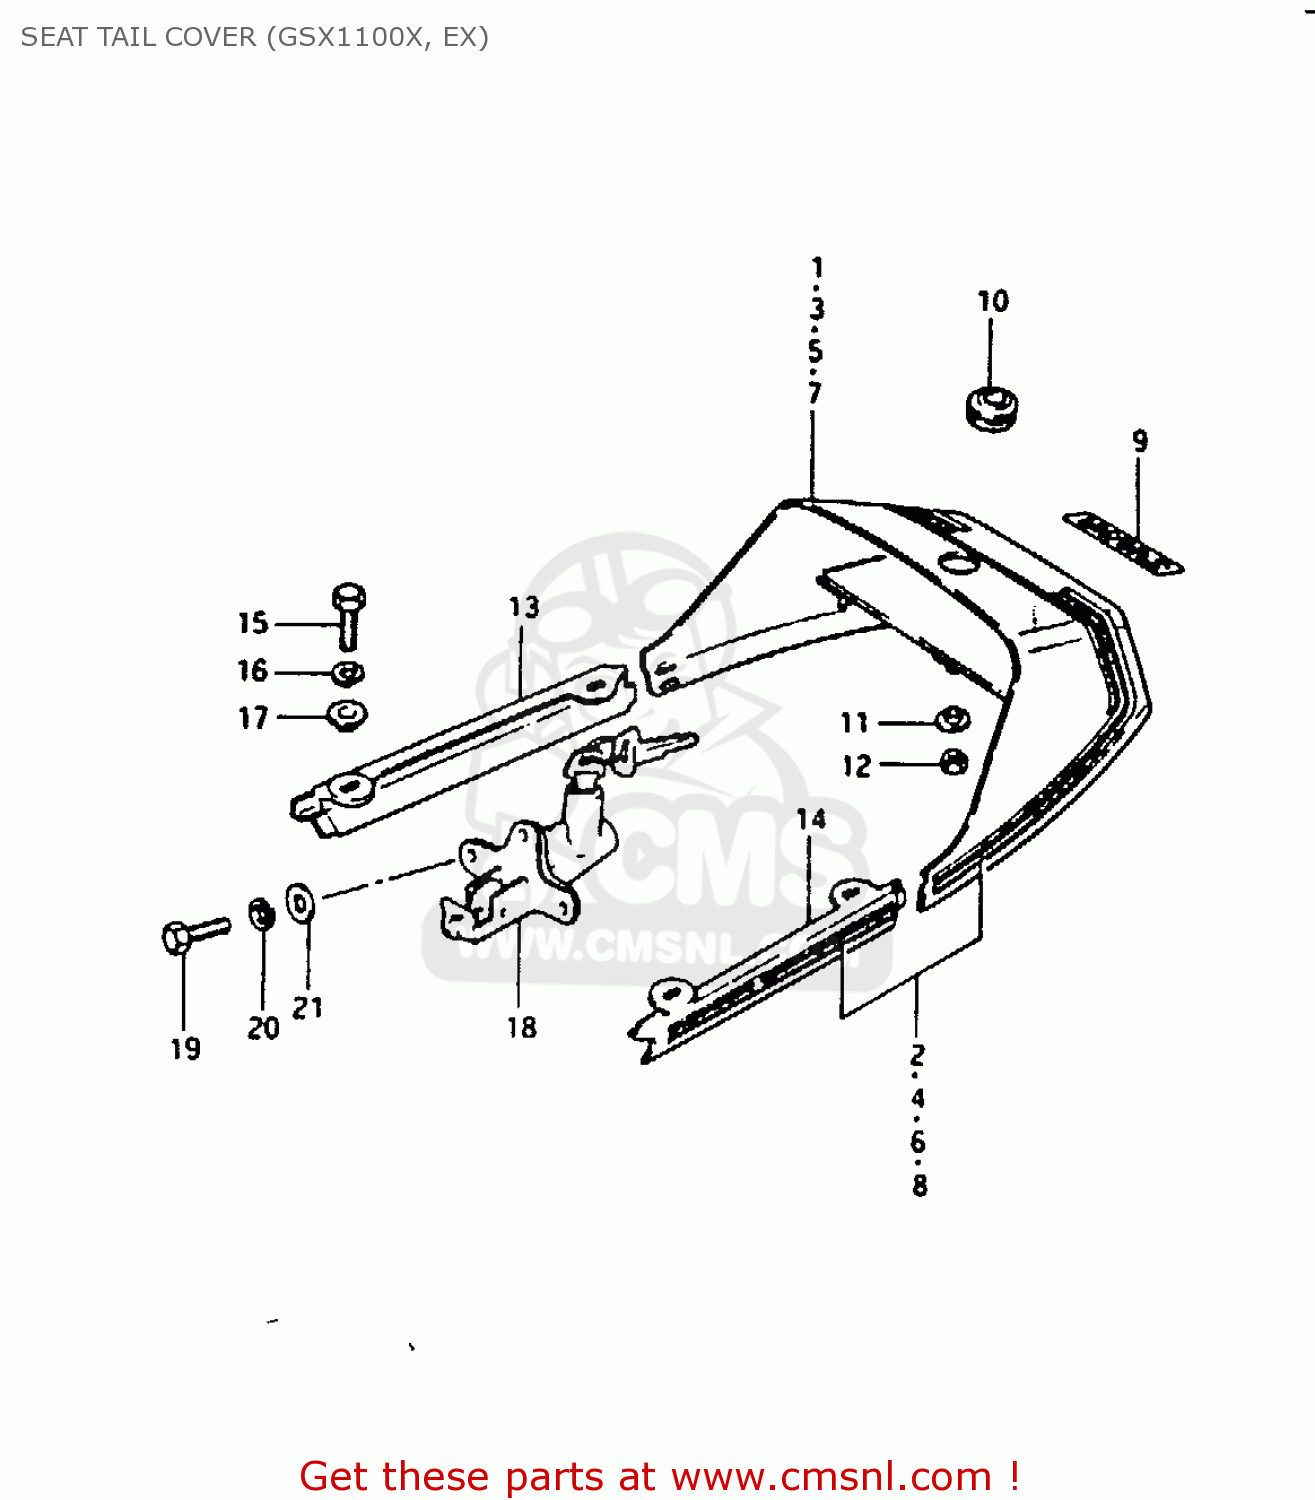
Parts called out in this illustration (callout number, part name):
1	COVER, SEAT TAIL (BLACK)
2	TAPE SET
3	COVER, SEAT TAIL (BLUE)
4	TAPE SET
5	COVER, SEAT TAIL (RED)
6	TAPE SET
7	COVER, SEAT TAIL (SILVER)
8	TAPE SET
9	EMBLEM (GOLD/BLACK)
10	GROMMET,SEAT LOCK HOLE
11	WASHER
12	NUT 6MM
13	MOLDING,SEAT
14	MOLDING,SEAT
15	BOLT
16	LOCK WASHER
17	WASHER
18	LOCK SET,SEAT
19	BOLT
20	LOCK WASHER
21	WASHER 6MM
